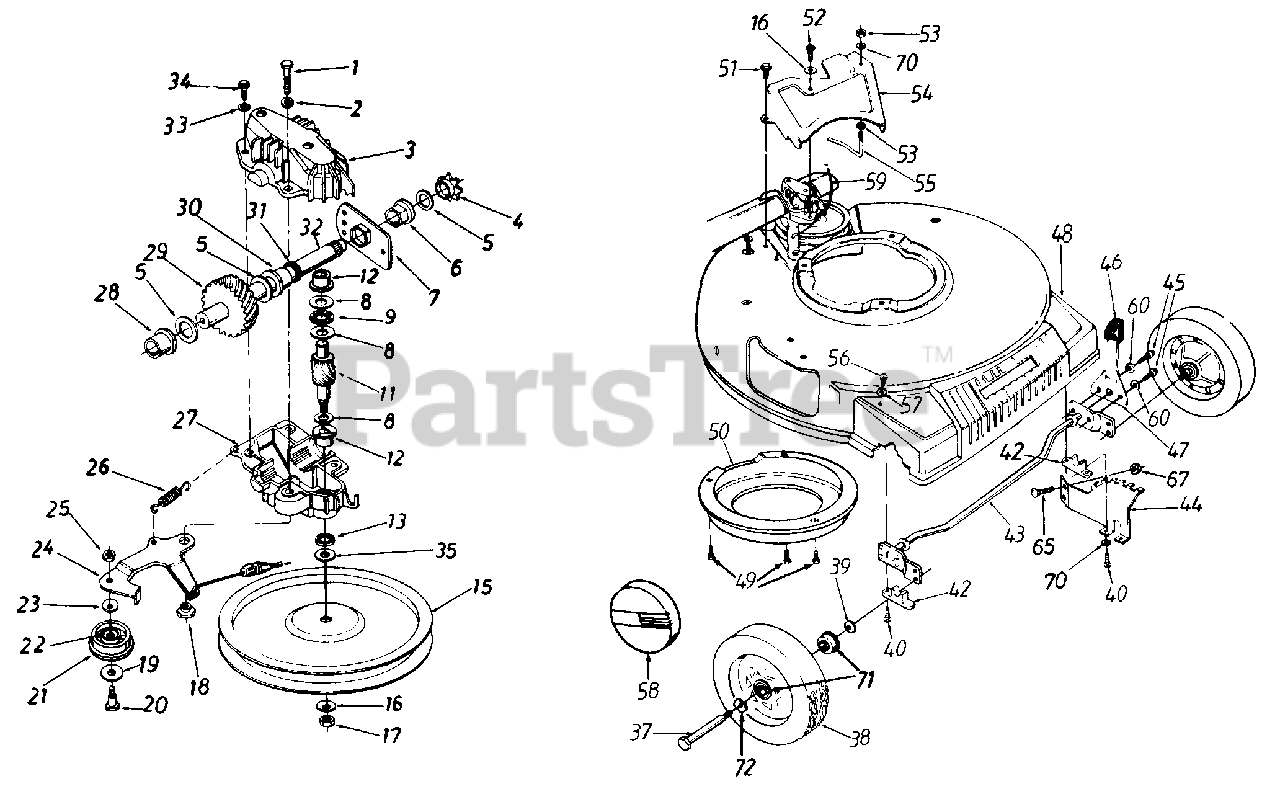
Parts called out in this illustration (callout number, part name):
1	Hex Patch Bolt 1/4-20 x 1.25"
2	L-Wash. 1/4" I.D.
3	Upper Hsg. Half
4	#48 Sprocket 7 T x 1/2 Pitch
5	Fl-Wash. 5/8" I.D. x .030
6	Hex Flange Brg. .631" I.D.
8	Thrust Wash. .382" I.D. x 70" O.D.
9	Thrust Bearing .375" I.D. x .812" O.D.
11	11 Tooth Pinion Shaft
12	Flange Bearing
13	Oil Seal
15	Fl-Pulley 5.06" O.D.
16	Bell-Wash. .265" I.D. x .75"
17	Hex L-Nut 1/4-28 L.H. Thd.
18	Shld. Spacer .375" Dia. x .170
19	Fl-Wash. .390" I.D. x 1.0"
20	Shld. Bolt .375" Dia. x .40"
21	Fl-Idler Plastic 1.50" Dia.
22	Needle Brg. .375" x .31
24	Idler Brk't. Ass'y.
25	Hex Patch L-Nut 1/4-28 Thd.
26	Extension Spring 1.12" Lg.
27	Lower Hsg. Half
28	Flange Bearing .566 Dia.
29	33 Tooth Helical Gear
30	Flange Bearing .629 Dia.
31	Oil Seal .625 Dia.
32	Gear Sprocket Shaft
33	L-Wash. #10 I.D
34	Hex B-Tap Scr. #10 x .62"
35	Hex Washer .26" x .88"
37	Front Axle Bolt
38	Wheel Ass'y. Comp.
39	Bell-Wash. .380" I.D. x .88
40	Hex Wash. Hd. Scr. 1/4 x 1" Lg.
42	Block Bushing
43	Axle Ass'y.
44	Height Adj. Bracket
45	Hex TT-Tap Scr. 1/4-20 x .38"
46	Knob
47	Spring Lever
48	Plastic Front End
49	Hex B-Tap Scr. 1/4" x .38"
50	Belt Cover
51	Hex Wash. Hd. TT-Scr. 1/4-20
52	Hex Wash. Hd. B-Tap Scr. 1/4 x .62" (Spec.)
53	Hex Nut 1/4-20 Thd.
56	Torx Truss Hd. Scr. 5/16 x .75"
57	Bell-Wash. .345" I.D. x .88"
58	Hub Cap
59	S.P. Cable
60	External L-Wash. 1/4" I.D.
65	Carr. Bolt 1/4-20 x .5" Lg.
67	Hex Flange L-Nut 1/4-20 Thd.
70	L-Wash. 1/4" I.D.
71	Wheel Bearing
